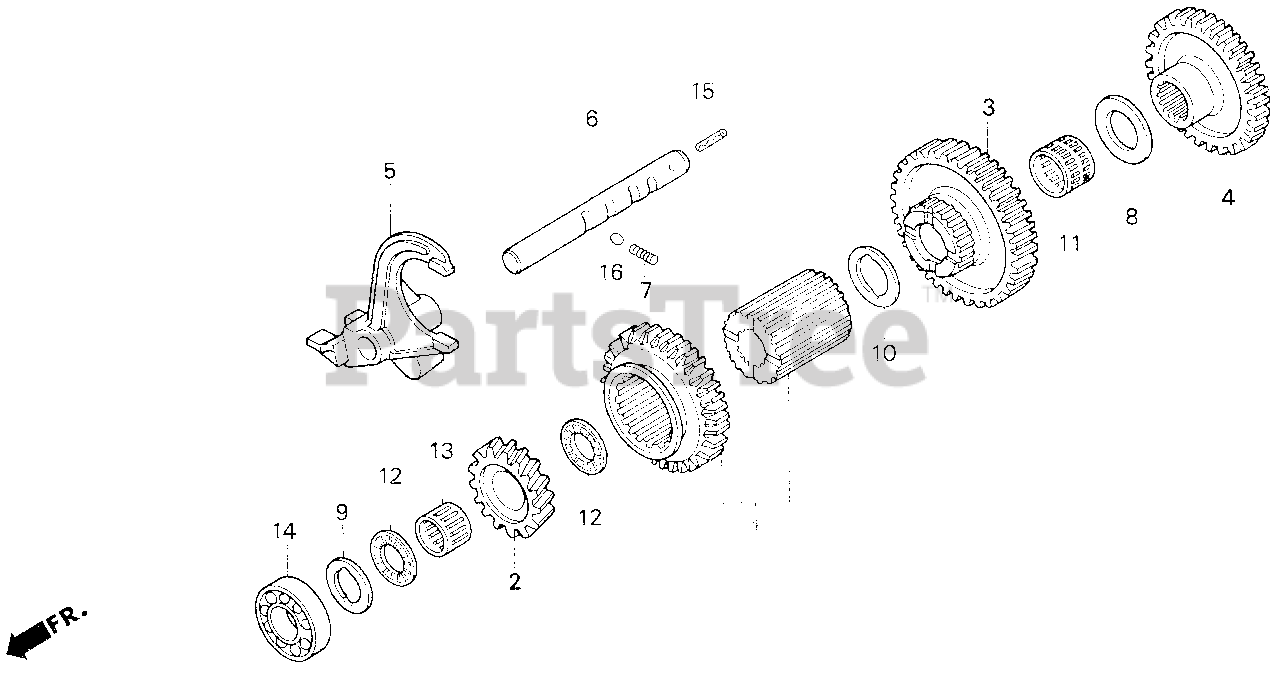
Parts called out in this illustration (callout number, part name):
1	CHANGE SET, AUXILIARY
2	GEAR, AUXILIARY DRIVEN HIGH (16T)
3	GEAR, L. AUXILIARY DRIVEN (48T)
4	GEAR, FR. DRIVE (29T)
5	FORK, AUXILIARY SHIFT
6	SHAFT, AUXILIARY SHIFT FORK
7	SPRING, BALL SETTING
8	WASHER, THRUST (25X40X2)
9	SHIM A, FINAL SHAFT (1.5MM)
9	SHIM B, FINAL SHAFT (2.0MM)
9	SHIM C, FINAL SHAFT (2.5MM)
10	WASHER, THRUST (25X35X2)
11	BEARING, NEEDLE (25X29X22) (TOYO)
12	NEEDLE, THRUST (20X35X2.8)
13	BEARING, NEEDLE (20X24X17)
14	BEARING, RADIAL BALL (6204) (TOYO)
15	PIN, SPRING (3X18)
16	BALL, STEEL (#10) (5/16)
